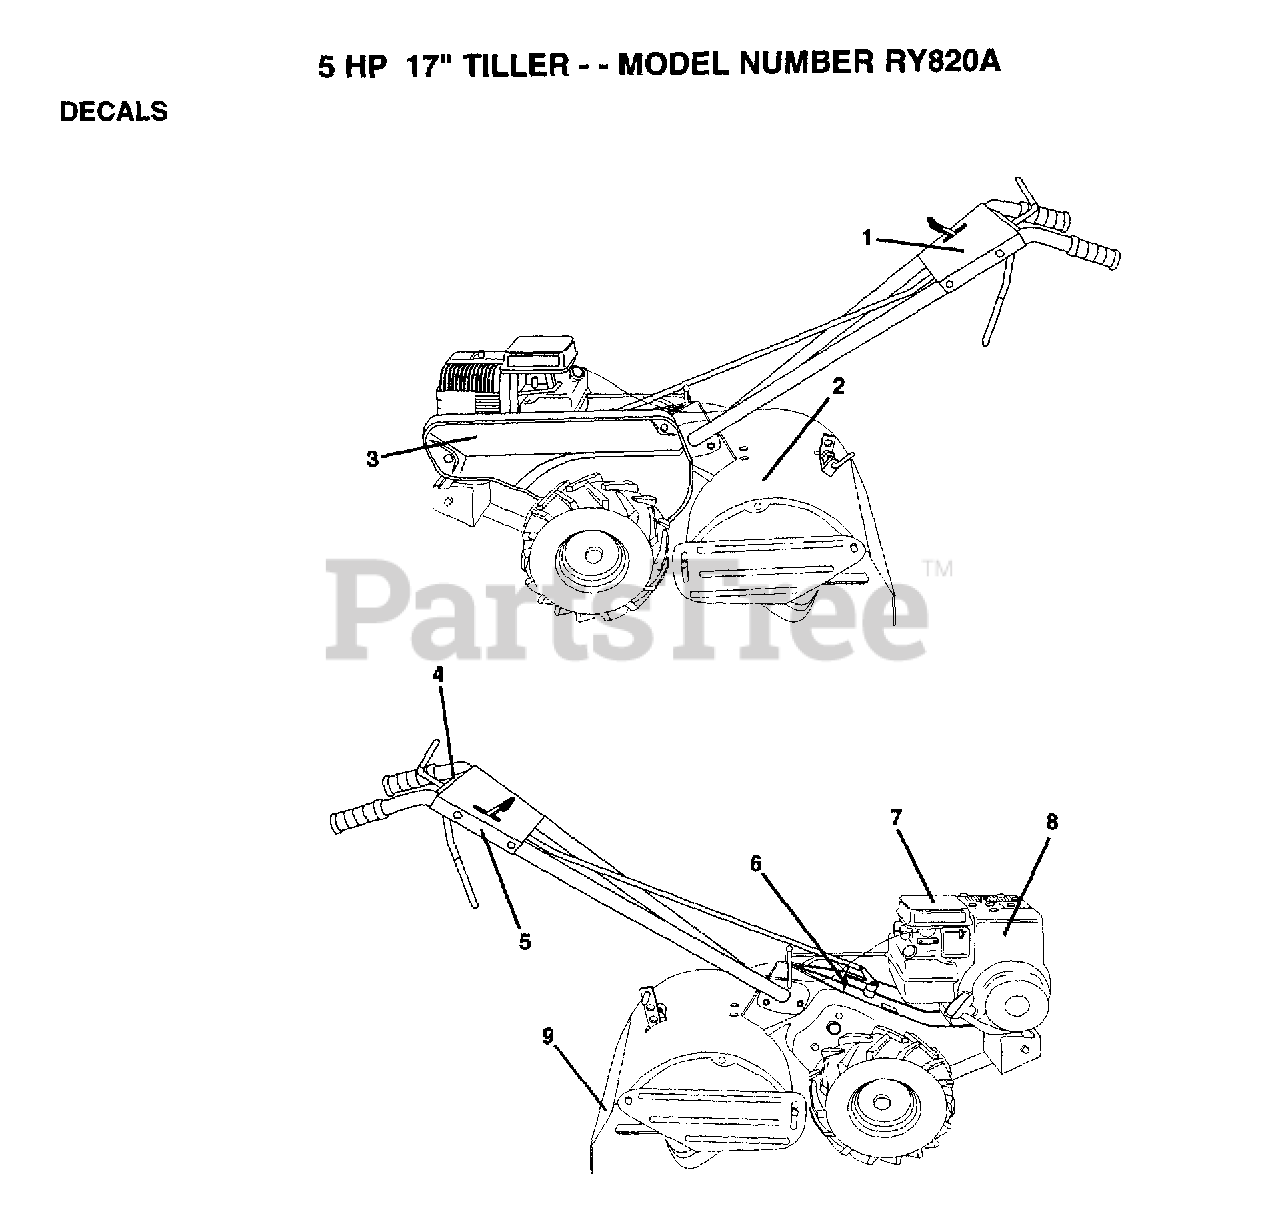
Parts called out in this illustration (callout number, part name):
3	DECAL, LOGO
5	DECAL TI
7	DECAL TI
